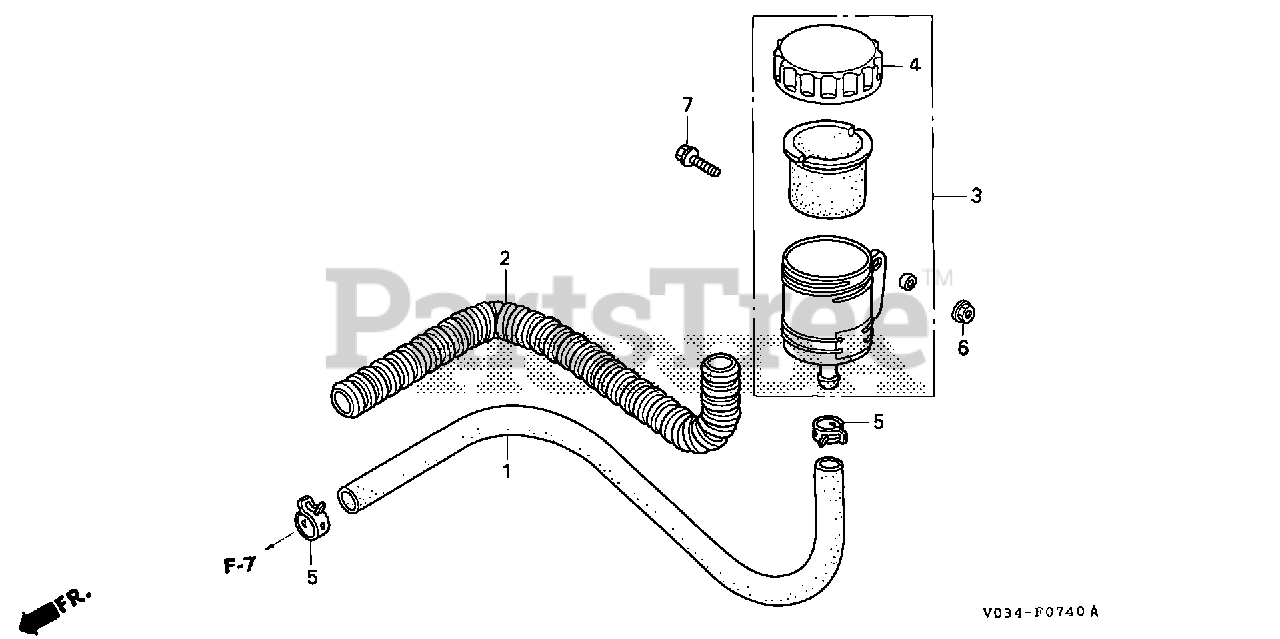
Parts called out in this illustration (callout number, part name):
2	PROTECTOR, OIL TUBE
3	TANK ASSY., OIL
4	BODY, OIL CAP
5	CLAMP D (19MM)
6	NUT, FLANGE (6MM)
7	BOLT, FLANGE (6X16)
